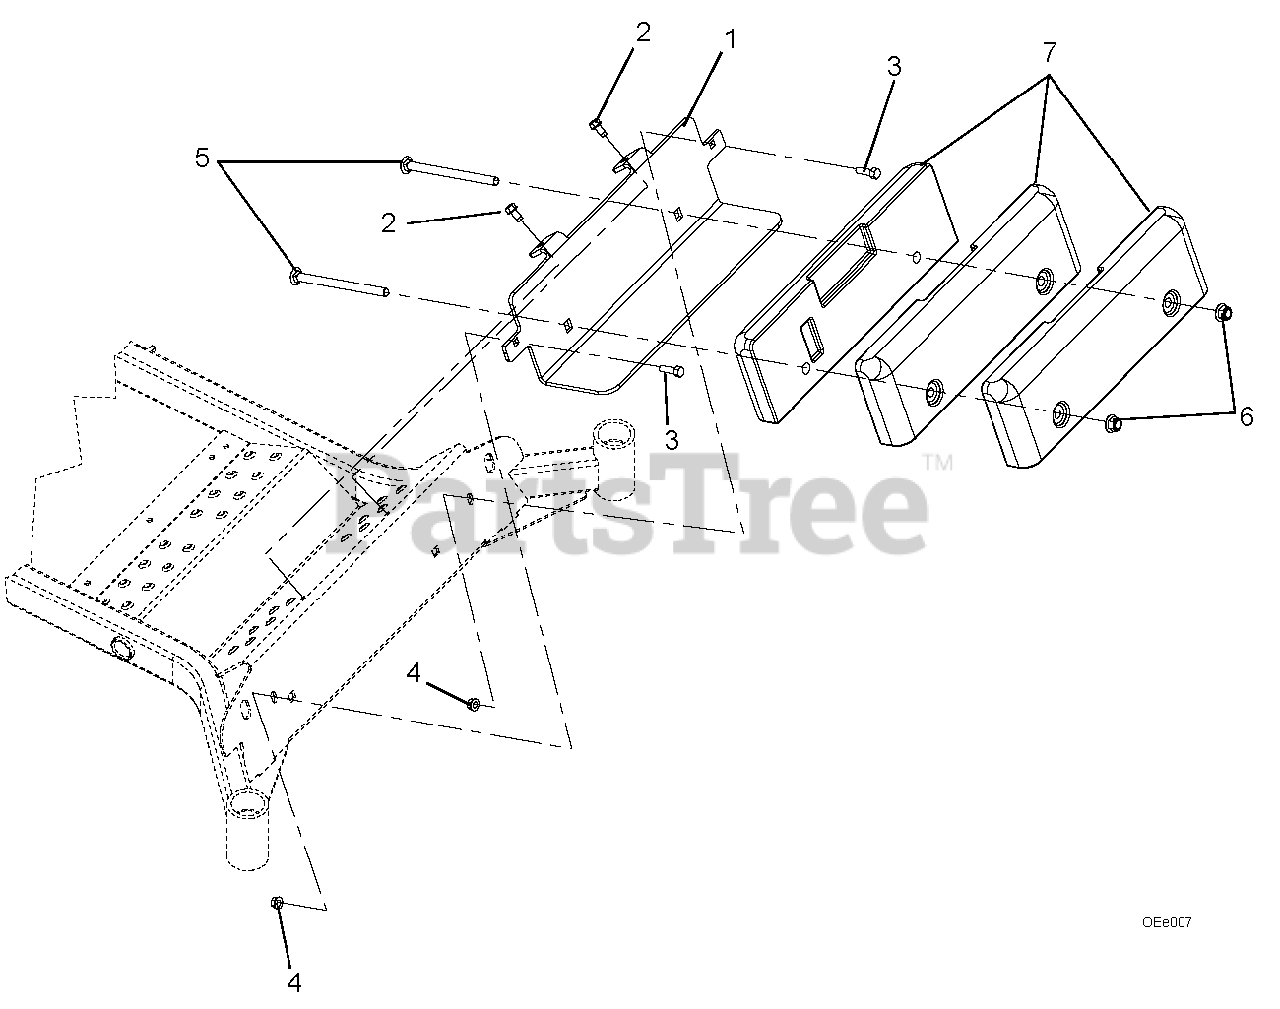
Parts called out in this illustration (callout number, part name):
1	Counterweight Bracket
2	Screw, .38-16 x .75 Self-Tapping
3	Bolt, Round Head Square Neck .38-16 x 1.25, Grade 5
4	Nut, Locking-Top-Flange .38-16
5	Bolt, Round Head Square Neck .50-13 x 7.00
6	Nut, Locking-Top-Flange .50-13
7	Counterweight
